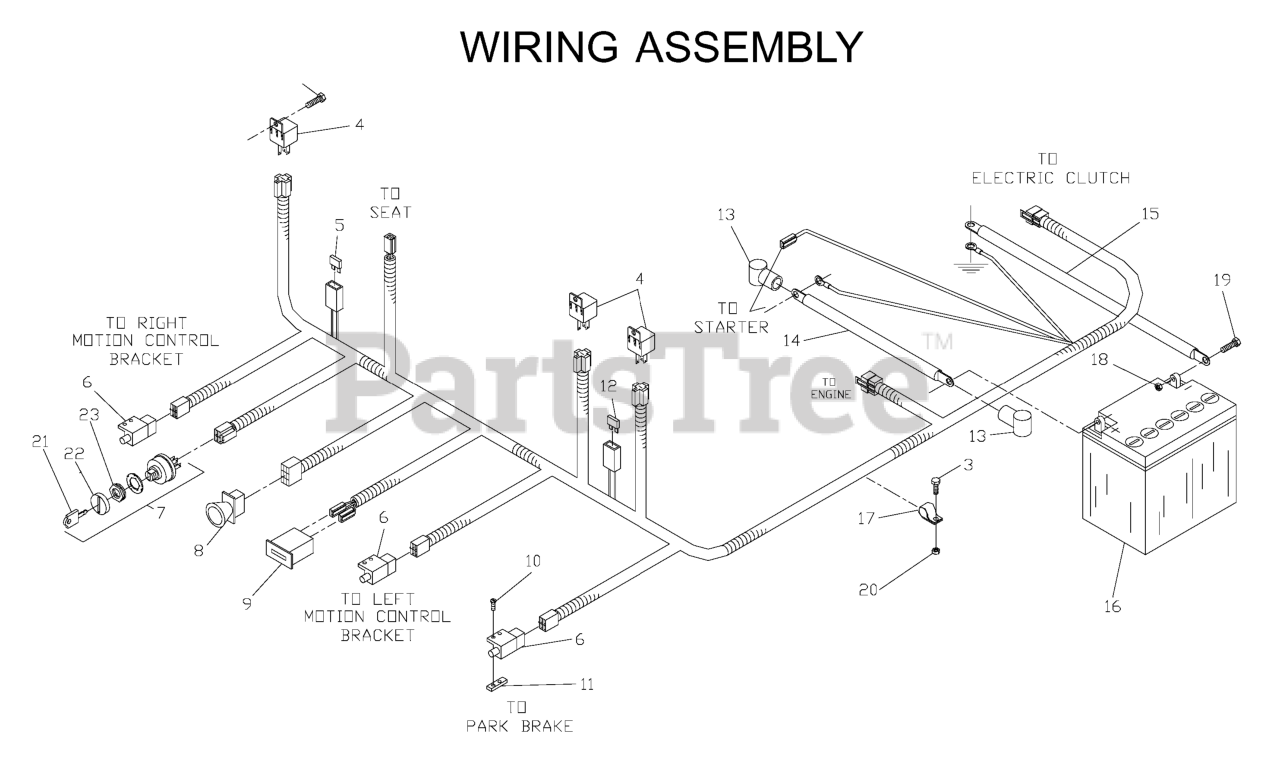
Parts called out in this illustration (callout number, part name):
1	WIRING HARNESS-KOH GEN I
2	SCREW #10 X 1/2 SELF TAPPING
3	HCS 1/4C X 3/4 HCS
5	FUSE, 7.5 AMP 32 VOLT ATO
6	SWITCH, INTERLOCK
7	IGNITION SWITCH KIT
8	RP.SWITCH, BLADE
9	HOUR METER
10	SCREW #10-24 X 5/8
11	TAPPED PLATE
12	FUSE, 20 AMP 32 VOLT ATO
14	CABLE POSITIVE
15	CABLE-NEGATIVE
16	BATTERY, 12 V 330 AMP
18	NUT 5/16C CENTERLOCK
19	SCREW 5/16C X 1 HEX CAP
20	NUT 1/4C CENTERLOCK
21	KEY-PADDED
22	DNO IGNITION NUT
23	CAP IGNITION NUT
